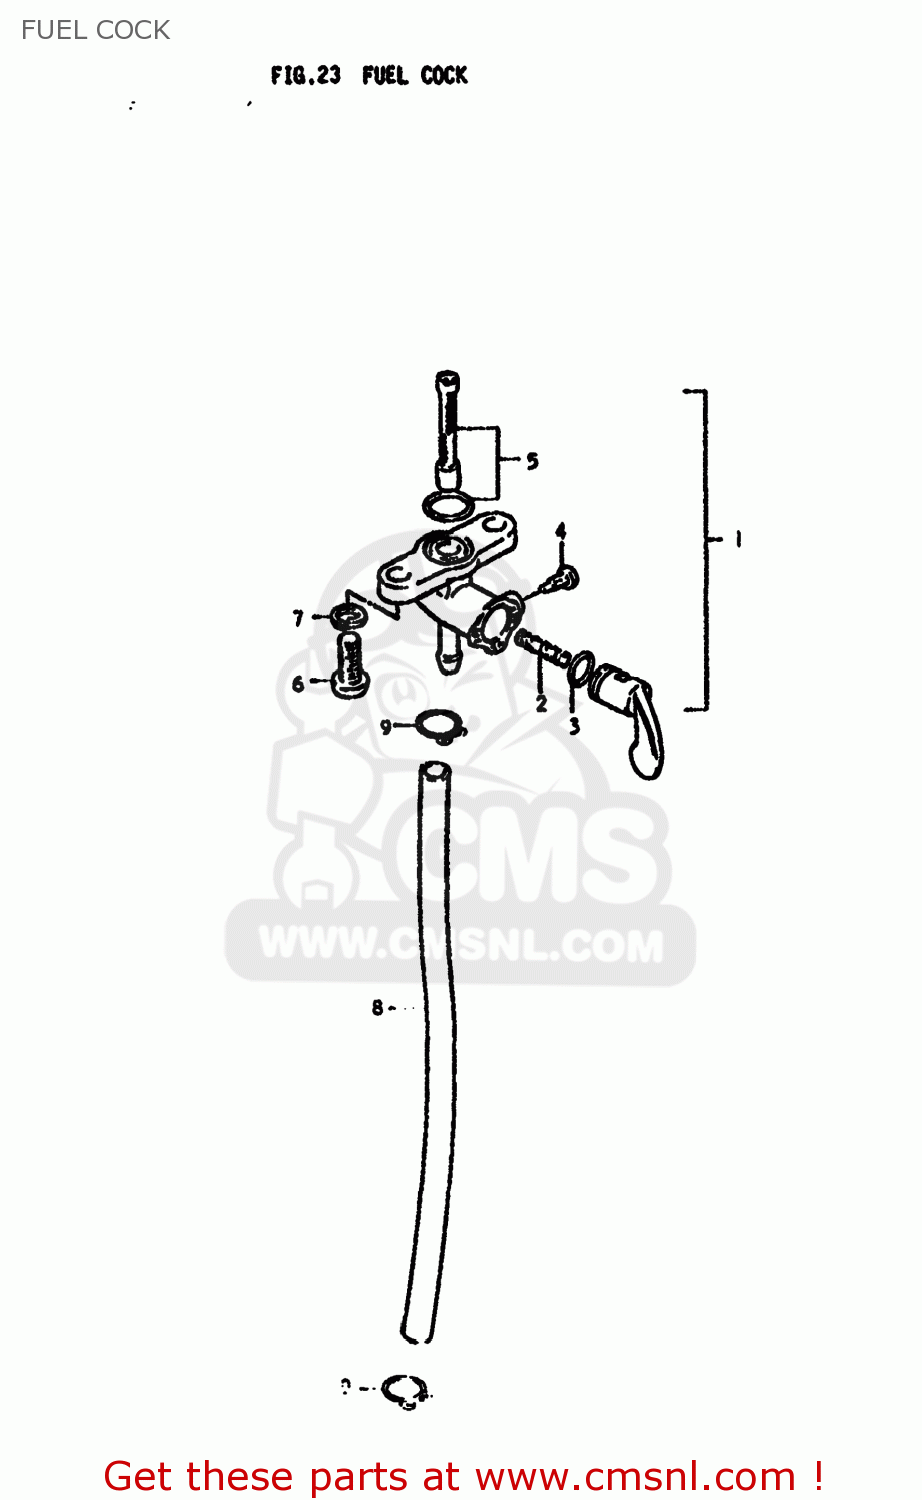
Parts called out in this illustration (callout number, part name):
1	COCK ASSEMBLY,FUEL
2	SPRING
3	O RING,LEVER
4	SCREW
5	FILTER SET FUEL
6	SCREW
7	LOCK WASHER
8	HOSE
9	CLIP
